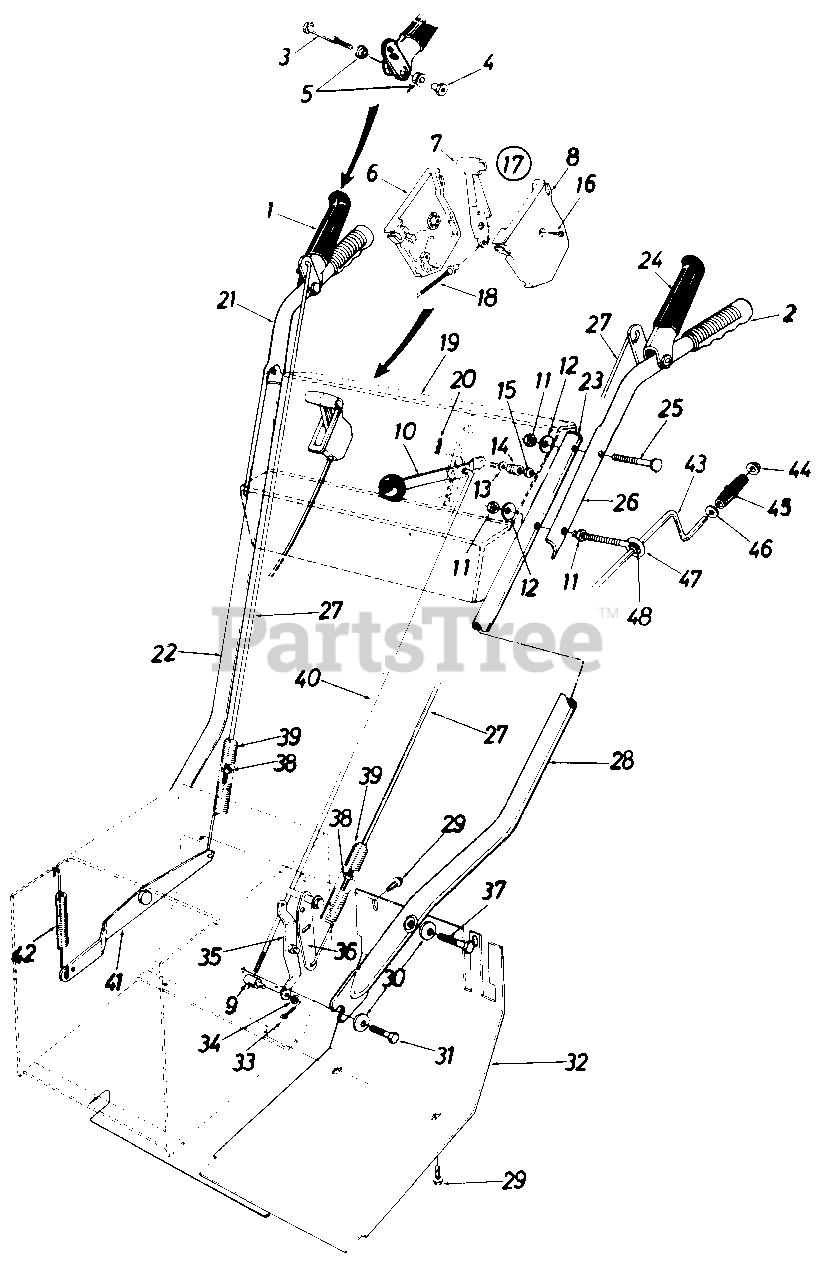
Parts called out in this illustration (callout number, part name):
1	Clutch Grip Ass'y.-R.H.
2	Grip
3	Shoulder Bolt .374 Dia. x 1.53" Lg.
4	Shld. Nut 1/4-20 Thd.
5	Hex Flange Plastic Bearing .38" I.D.
9	Adjustment Ferrule
10	Shift Handle Ass'y.
11	Hex Nut 5/16-18 Thd.
12	Bell-Wash. .34" I.D. x .88"O.D.
13	Bell-Wash. .40" I.D. x .88"O.D.
14	Compression Spring
15	Hex Ins. L-Nut 3/8-24 Thd.
17	Throttle Control Box Ass'y.
18	Throttle Control Wire
19	Handle Panel Ass'y.
20	Int. Cotter Pin 5/16" Dia.
21	Upper Handle-R.H.
22	Lower Handle-R.H.
23	Plastic Plug
24	Clutch Grip Ass'y.-L.H.
25	Curved Carriage Bolt 5/16-18 x 2.0" Lg.
26	Upper Handle-L.H.
27	Lockout Rod
28	Lower Handle-L.H.
29	Hex Wash. Hd. Self-Tap Scr. 5/16-24 x .50" Lg.
30	Bell-Wash. .40" I.D. x .88" O.D.
31	Pilot Hex Scr. 3/8-16 x .88" Lg.
32	Frame Cover
33	Cotter Pin 3/32" Dia.*
34	Fl-Wash. .345 I.D. x .62 O.D. x .06
35	Shifting Linkage Brkt.
36	Drive Clutch Brkt. Ass'y.
37	Hex Bolt 3/8-16 x 2.0" Lg.
38	Hex Ins. L-Nut 1/4-20 Thd.
39	Ext. Spring .75" O.D. x 5" Lg.
40	Shift Rod
41	Auger Clutch Brkt.
42	Ext. Spring .38" O.D. x 3.18" Lg.
43	Chute Crank Ass'y.
44	Push Nut 3/8" Rod
45	Knob 3/8" Rod
46	Fl-Wash. .40" I.D. x .62" O.D.
47	Eyebolt 5/16-18 x 5.0" Lg.
48	Grommet
